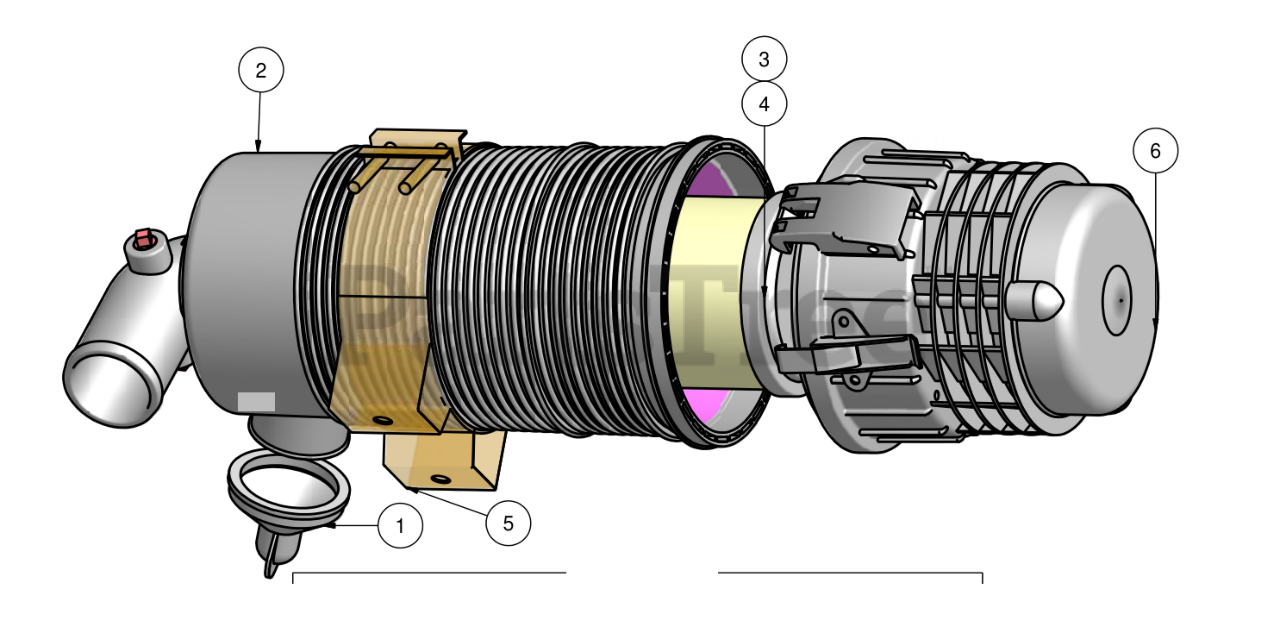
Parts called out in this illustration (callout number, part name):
1	Debris Plug
2	Canister Body
3	Inner Filter
4	Outer Filter
5	Mounting Bracket
6	Diesel Air Filter
